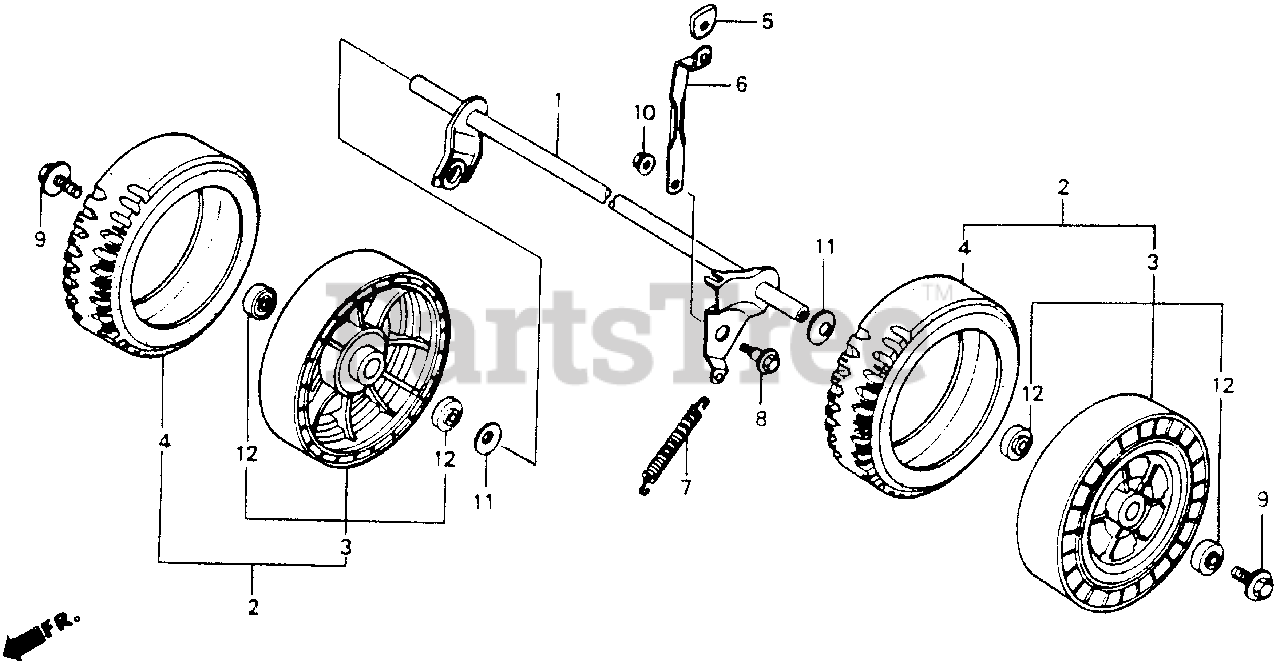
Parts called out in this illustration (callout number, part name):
1	SHAFT, RR. AXLE
2	WHEEL (8") *NH31* (MCKINLEY WHITE)
3	HUB, WHEEL (NA USE ALT:42710-VA3-J00)
4	TIRE (8 INCH)
5	GRIP, ADJUSTER
6	PLATE, RR. ADJUSTER
7	SPRING, RR. BALANCER
8	BOLT, ADJUSTER ARM
9	BOLT, WHEEL
10	NUT, FLANGE (8MM)
11	WASHER, SPRING
12	BEARING, RADIAL BALL
